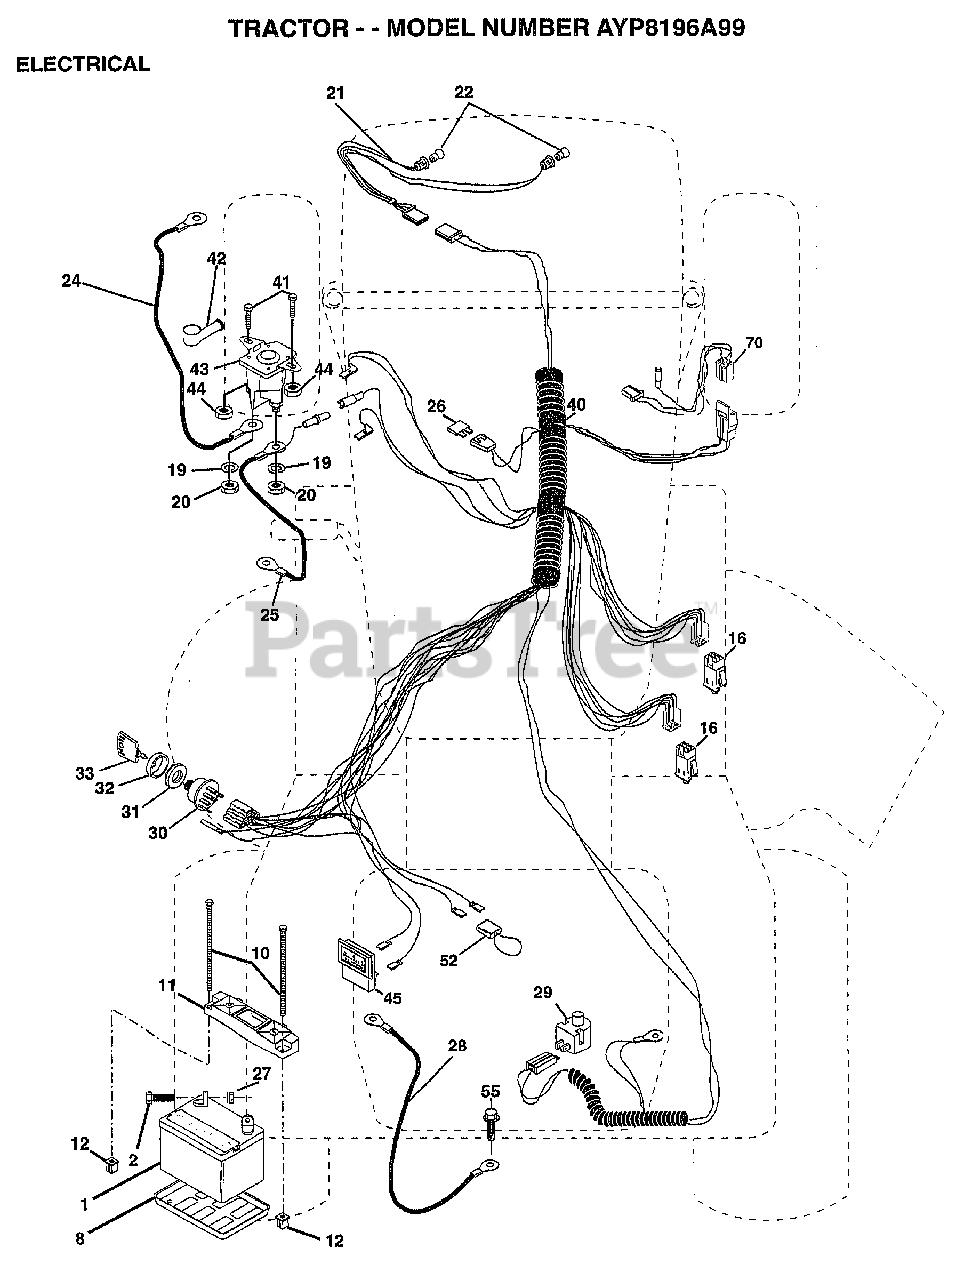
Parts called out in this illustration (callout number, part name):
2	BOLT LT
8	"TRAY T, BATTERY"
11	HOLDDOWN BATTERY
16	SWITCH INTERLOCK
20	NUT
21	HARNESS.ASM.LIGHT W/4152J
22	HEADLAMP BULB
24	"CABLE T, BATTERY"
25	CABLE.6GA.22W/16W
26	FUSE.15 AMP
27	NUT
28	CABLE.GRND.6GA.21
29	SWITCH SEAT
30	SWITCH IGN 4POS
31	NUT IGNITION
32	COVER KEY SWITCH
33	KEY
40	HARNESS.IGNITION
41	BOLT HXHD FIN
44	NUT HXKEP 1/4X20
52	PROTECTION LOOP
55	SCREW LT
70	HARNESS.ENGINE
